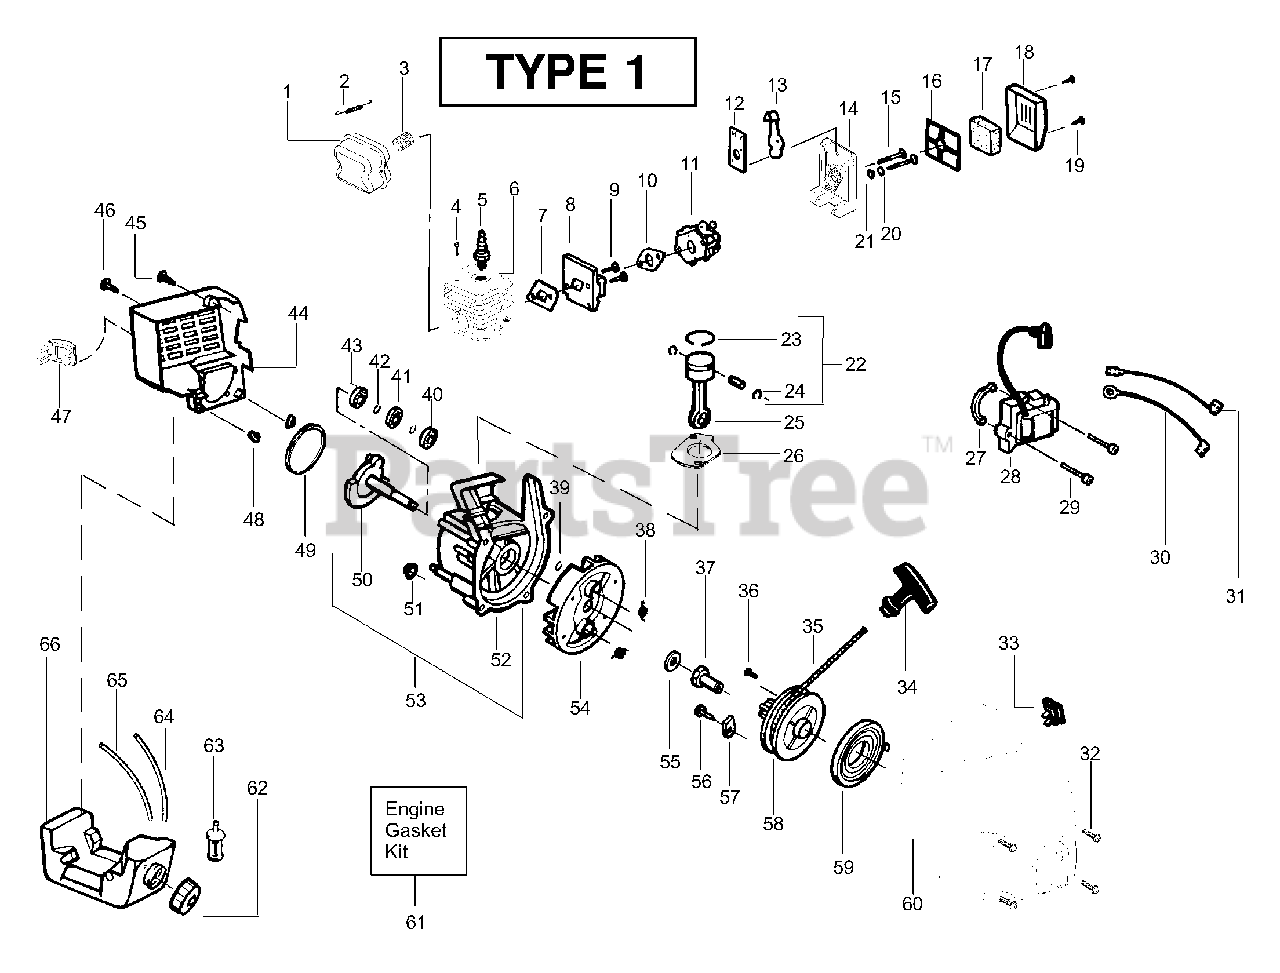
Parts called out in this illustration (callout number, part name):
1	Kit - Muffler
2	Muffler Spring
3	Screen-Spark Arrestor
4	Screw-Cylinder
5	Spark Plug (RCJ-8Y)
6	Kit - Cylinder
7	Gasket-Cyl./Carb.(kit)
8	Kit - Carb. Adaptor
10	Gasket-Carb.(kit)
11	Kit - Carburetor Ass'y
12	Choke Plate Mounting
13	Choke Shutter
16	Plate - Filter Support
17	Air Filter Foam
18	Air Filter Cover
20	Spacer-Choke
22	Kit - Piston
23	Piston Ring
24	Piston Pin Retainer
25	Connecting Rod Ass'y.
26	Gasket-Cylinder (kit)
27	Spacer-Module
28	Ignition Module
30	Ground Wire Ass'y.
31	Lead Wire Ass'y.
32	Screw
33	Kit - Switch
34	Starter Handle
35	Kit - Rope
37	Drive Coupling
38	Starter Dog Spring
39	Retainer Ring-C'case
40	Outer Bearing
41	C'case Seal
42	Retain. Ring-C'shaft
43	Inner Bearing
44	Rear Shroud
46	Screw
47	Guard-Muffler
48	Isolator-Shroud
49	O-Ring-C'case (kit)
50	Crankshaft Ass'y.
51	Isolator-C'Case
52	Crankcase Ass'y.
53	C'case & C'shaft Assy.
54	Flywheel Ass'y.
55	Washer-Flat
57	Retainer-Can
58	Starter Pulley Kit
59	Starter Spring
60	Assy. - Fan Housing
61	Kit-Engine Gasket
62	Fuel Cap Ass'y.
63	Fuel Pickup Ass'y.
64	Kit-Fuel Line (Small)
65	Kit-Fuel Line (Large)
66	Fuel Tank Ass'y
